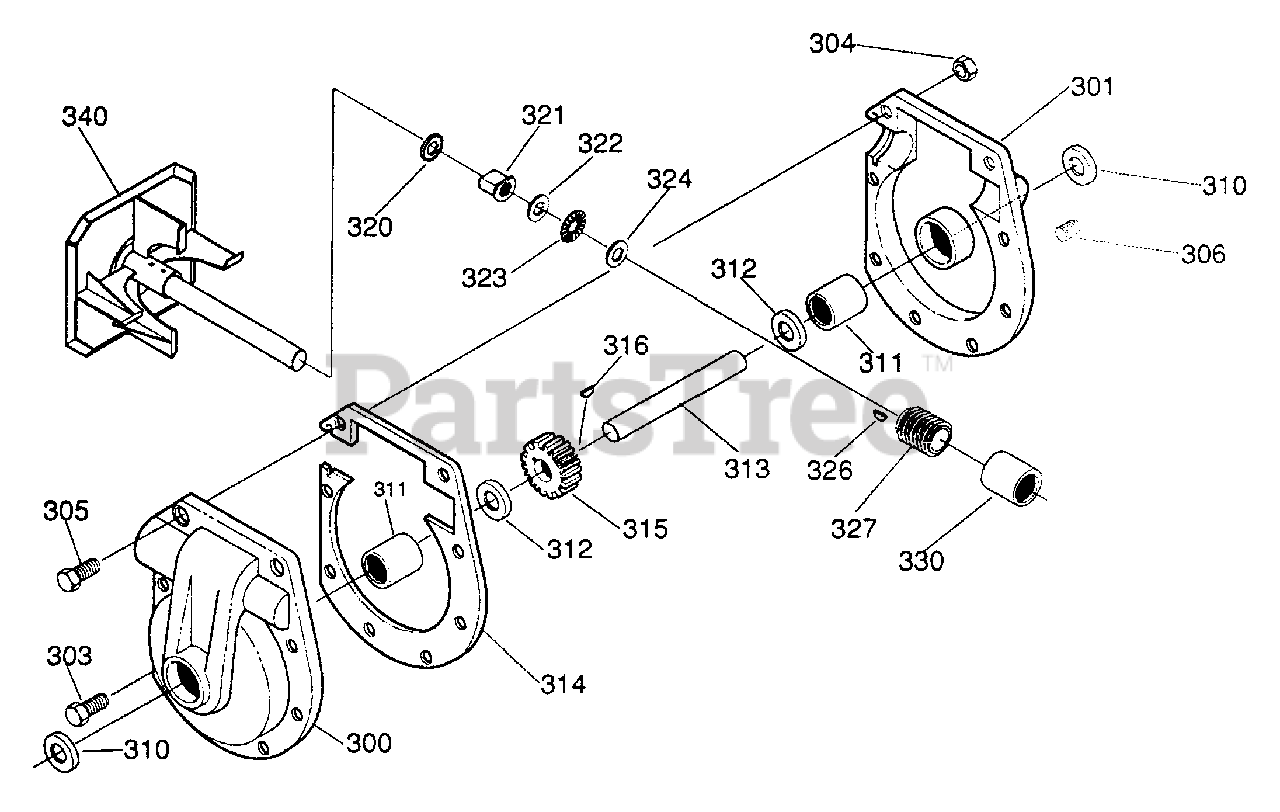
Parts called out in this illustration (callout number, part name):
300	CASE, GEAR, RH
301	CASE, GEAR, LH
303	SCREW, 5/16-24 x 1.00 HHC
304	NUT, 5/16-24 HEXWDFLLK
305	SCREW, 5/16-24 X 1.50 HHC
310	SEAL, OIL CR 530552 #53744
311	BEARING, SLEEVE
312	FLATWASHER
313	SHAFT, AUGER OUTPUT MF 22"
314	GASKET, GEAR BOX
316	KEY, WDRF #91 .75 DIA x .25 WD
320	RING, QUAD
321	BEARING, FL .753 ID x 1.128 OD x 1.03
322	FLATWASHER, .752 x 1.24 x .093 PL
323	BEARING, ROLL
324	FLATWASHER, .752 x 1.24 x .093 PL
326	KEY, HI-PRO 606 .75 DIA x .187 WD
330	BEARING, SLEEVE .752 ID x .88 OD x .755
580	IMPELLER ASSEMBLY
